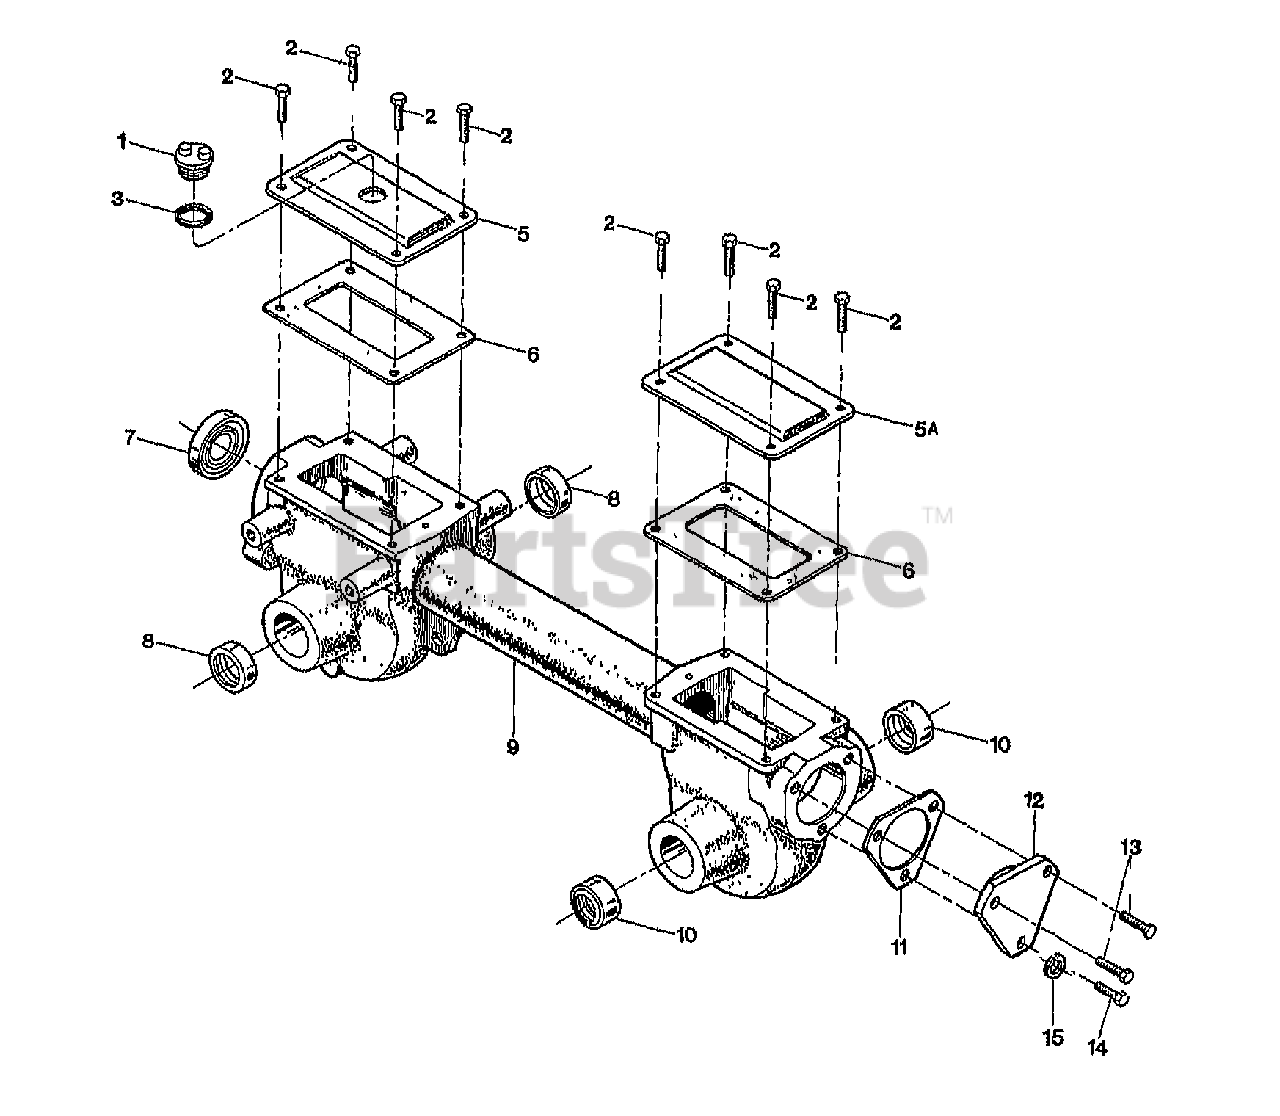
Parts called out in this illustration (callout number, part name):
1	PLUG-OIL FILL 3/4-10
2	SCR-HFLK 5/16-18X.62 G5ZP
3	GASKET-O RING .674 I.D.
5	COVER-TRANS FRNT PNT
5A	CVR-TRANS REAR PNT
6	GASKET-GEAR HSG
7	SEAL-OIL DRIVESHAFT
8	SEAL-OIL WHEELSHAFT
9	TRANSMISSION-MACH
9	HSG-TRANS T/B TUFFY {12155}
10	KIT-OIL SEAL TUFFY
11	GASKET-BEARING CAP .010
11	GASKET-BEARING CAP .030
12	CAP-REAR BEARING-PM
13	SCR-HFLK 5/16-18X1.00 ZP
14	SCR-HFLK 5/16-18X.75 ZP
15	WASHER-LK .312 ZP
